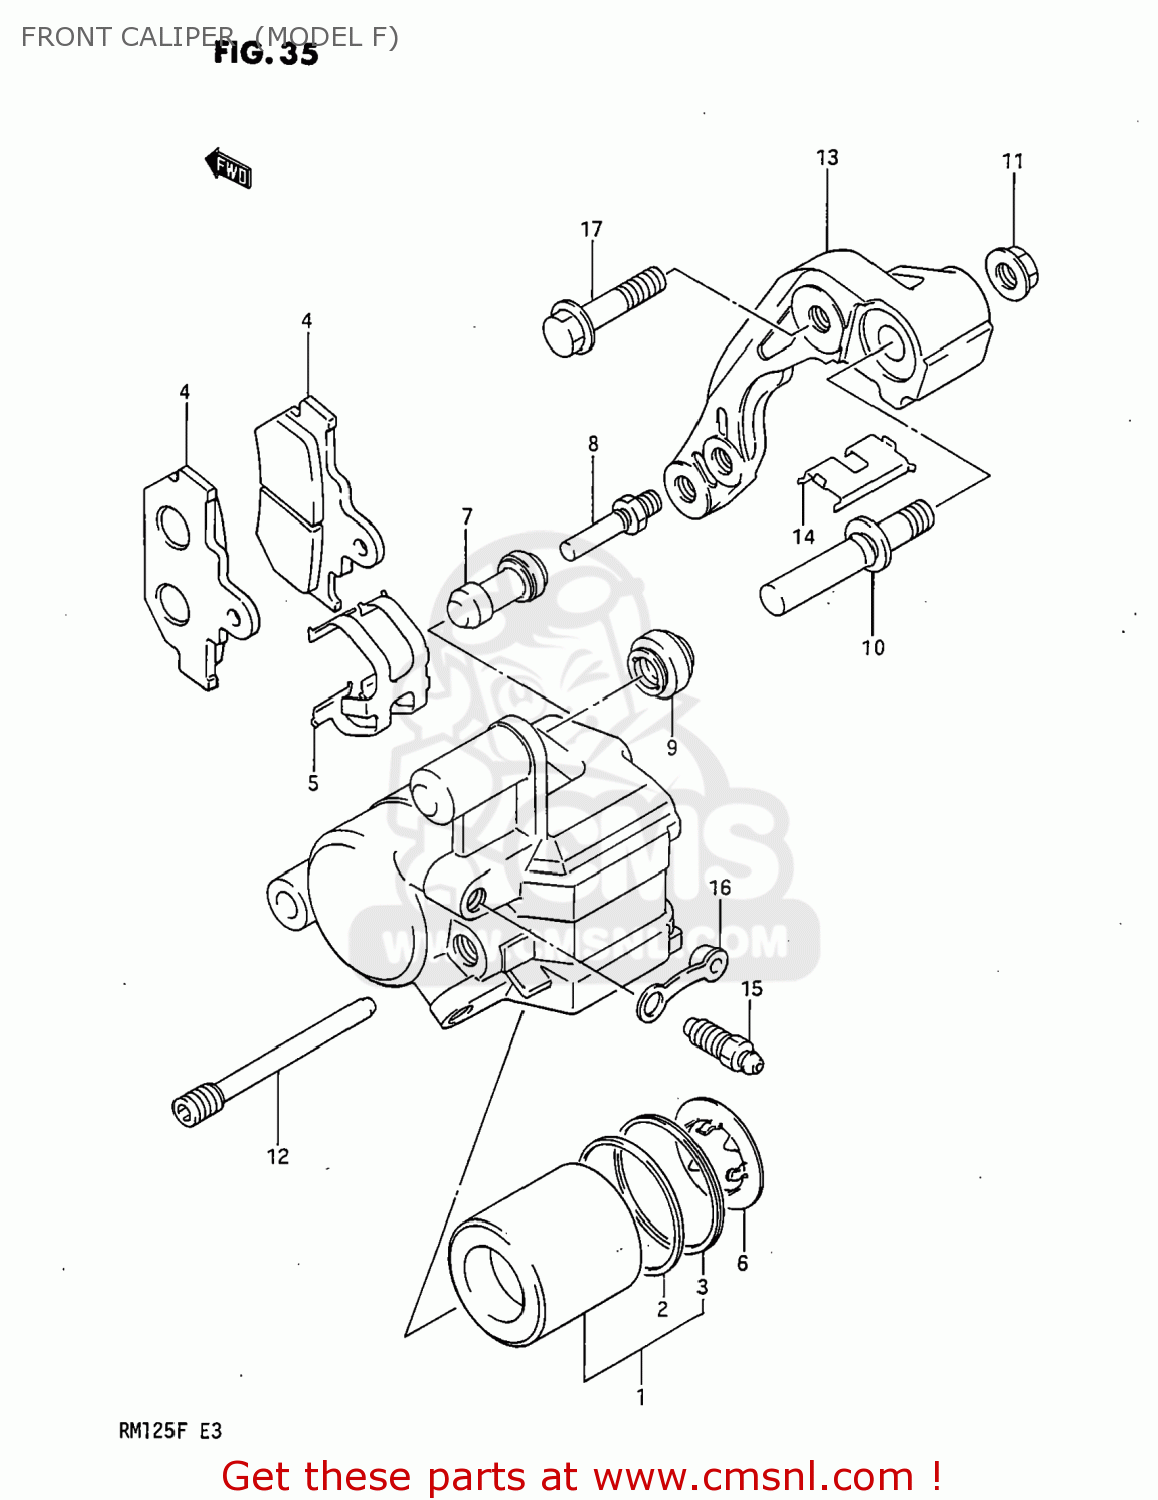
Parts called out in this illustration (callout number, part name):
1	PISTON SET,CALIPERS
2	SEAL,PISTON
3	DUST SEAL,PISTON
4	PAD
5	SPRING
6	SHIM
7	BOOT
8	PIN,BOLT
9	BOOT
10	PIN,SLIDE
11	NUT,SLIDE PIN
12	PIN,HANGER
13	BRACKET
14	RETAINER
15	BLEEDER
16	CAP,BLEEDER
17	BOLT
